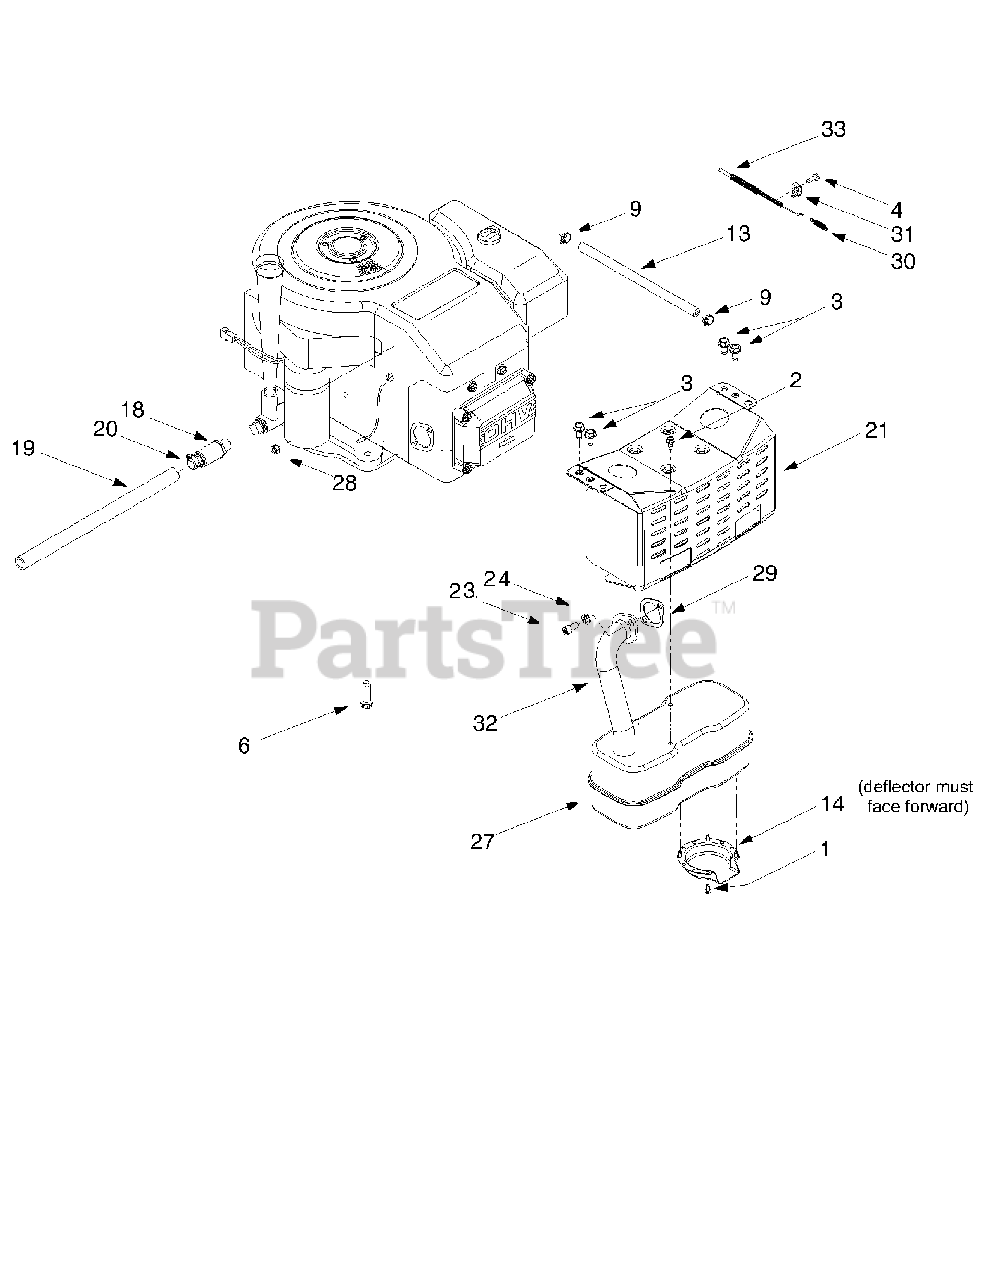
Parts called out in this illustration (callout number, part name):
1	Self Tapping Screw, #8-32 x .375
2	Self Tapping Screw, 1/4-20 x .5
3	Self Tapping Screw, 5/16-18 x .625
4	Screw, #10-32 x .625
6	Self Tapping Screw, 3/8-16 x 1.25
9	Hose Clamp
13	Fuel Line Hose
14	Muffler Deflector
18	Oil Drain Valve
19	Oil Drain Hose
20	Oil Drain Cap
23	Socket Cap Screw, 5/16-18 x .625
24	Lock Washer, 5/16
27	Muffler, Single Inlet
28	Hex Sems Nut, 1/4-20 (for starter cable)
29	Exhaust Gasket (Vanguard Single) 1600
30	Extension Spring, .275 x 1.25
31	Casing Clamp
32	Exhaust Pipe (Vanguard Single) 1600
33	Throttle/Choke Cable (Vanguard Single) 1600
